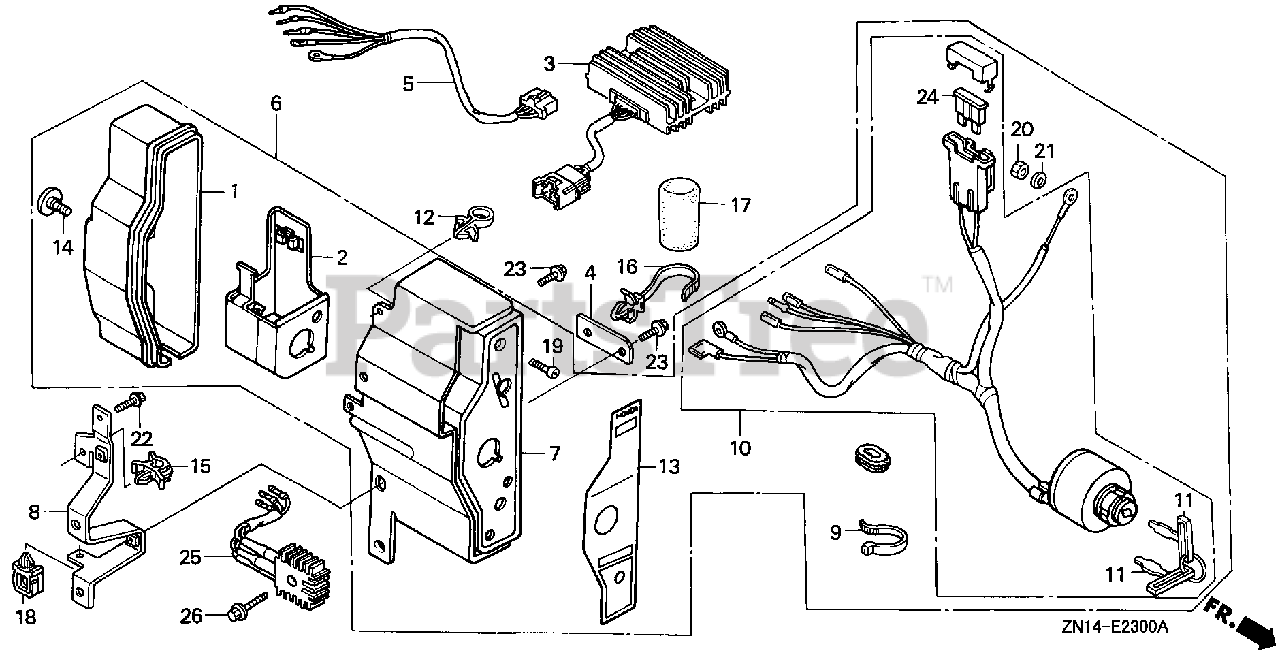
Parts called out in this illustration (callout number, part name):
1	CASE, CONTROL
2	BRACKET, CASE MOUNTING
4	BRACKET, WIRE HARNESS CLIP
6	BOX ASSY., CONTROL
7	PANEL, CONTROL
8	STAY, CONTROL BOX
9	BAND
10	SWITCH ASSY., COMBINATION
11	KEY
12	HOLDER, STOP SWITCH WIRE
13	MARK, CONTROL BOX (EXTERNAL-REGULATOR)
14	SCREW, SPECIAL (6X12)
15	CLIP, WIRE HARNESS
16	BAND, WIRE HARNESS (150MM) (BLUE)
17	TUBE, CORD (30MM)
18	CLIP, WIRE HARNESS
19	SCREW, PAN (4X12)
20	NUT, HEX. (4MM)
21	WASHER, SPRING (4MM)
22	BOLT, FLANGE (6X10)
23	BOLT, FLANGE (6X12)
24	FUSE, BLADE (25A)
25	RECTIFIER ASSY.
26	BOLT, FLANGE (6X32)
